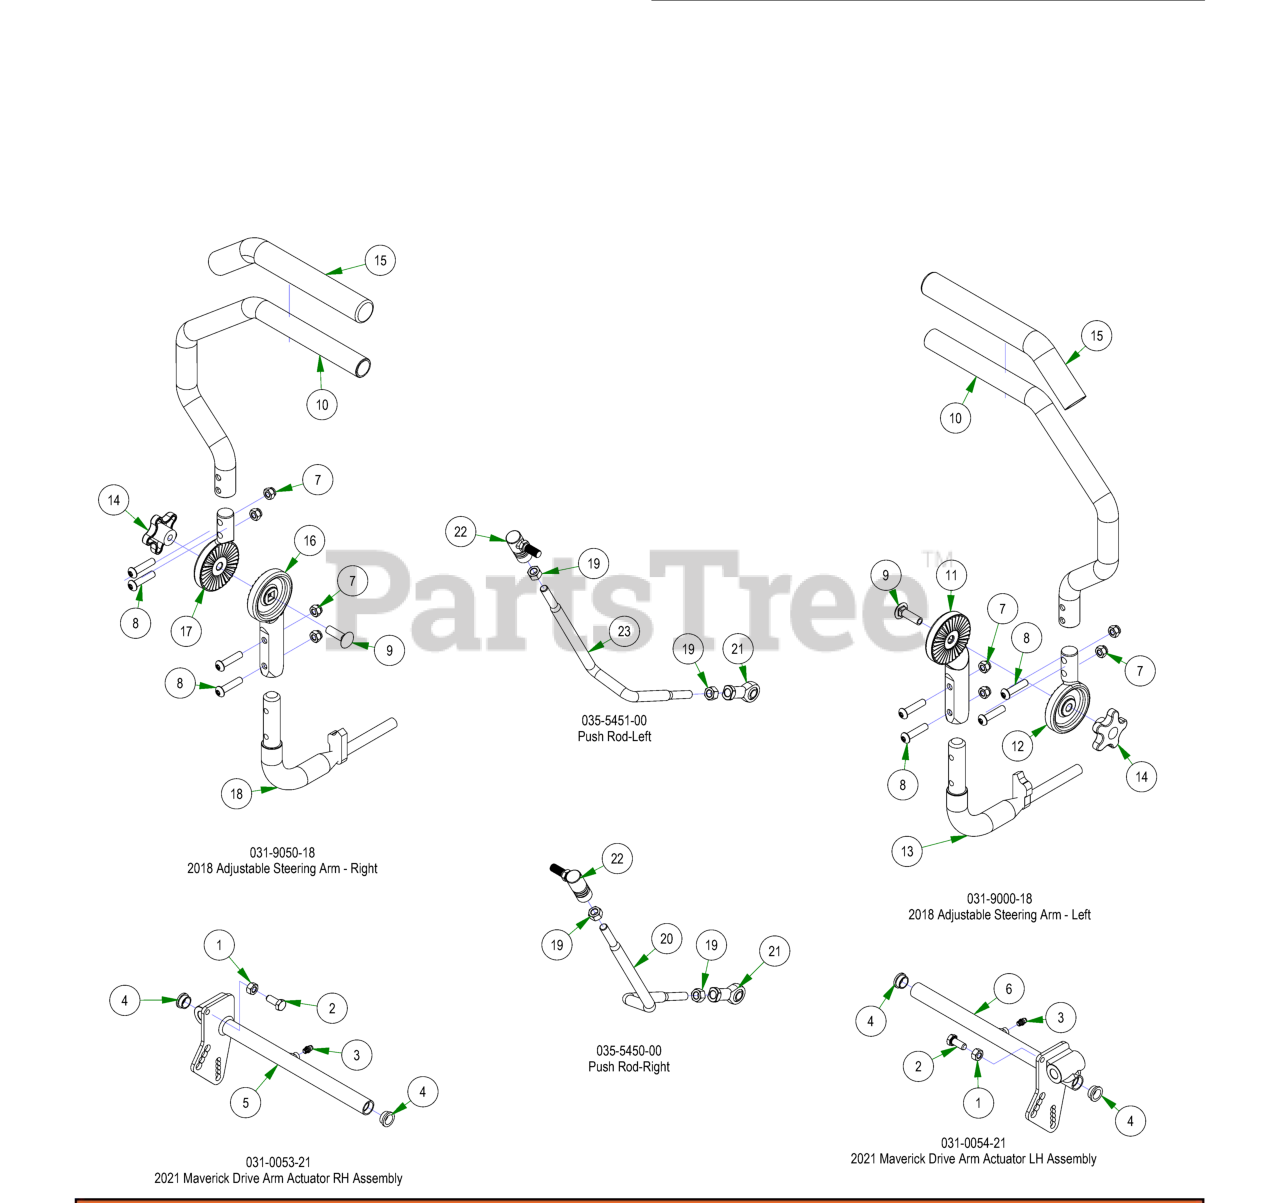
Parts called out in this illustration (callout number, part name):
1	5/16-18 HEX NUT ZINC
2	5/16-18 X 3/4 HEX CAP SCREW (GR.5) ZINC
3	1/4" Press in Grease Fitting
4	2019 Drive Arm Bushing
5	2021 Drive Actuator RH Weldment
6	2021 Drive Actuator LH Weldment
7	5/16-18 NYL INS L/N ZC
8	5/16-18 UNC X 1-3/8" BHCS, TORX DRIVE, GR 5
9	3/8-16 X 1-1/4 CARRIAGE BOLT ZINC
10	Upper Tube-Adjustable Steering
11	2018 Lower Adjuster - Steering Arm- Left
12	2018 Upper Adjuster - Steering Arm- Left
13	Steering Arm Elbow (Left)
14	Black Knob for Adjustable Steering Arm
15	Rubber Grip
16	2018 Lower Adjuster - Steering Arm- Right
17	2018 Upper Adjuster - Steering Arm- Right
18	Steering Arm Elbow (Right)
19	3/8" Fine Threaded Jam Nut
20	Push Rod - Right (Rod Only)
21	Spherical Rod End - Outlaw
22	Quick Release Ball Joint
23	Push Rod LH (Rod Only)
